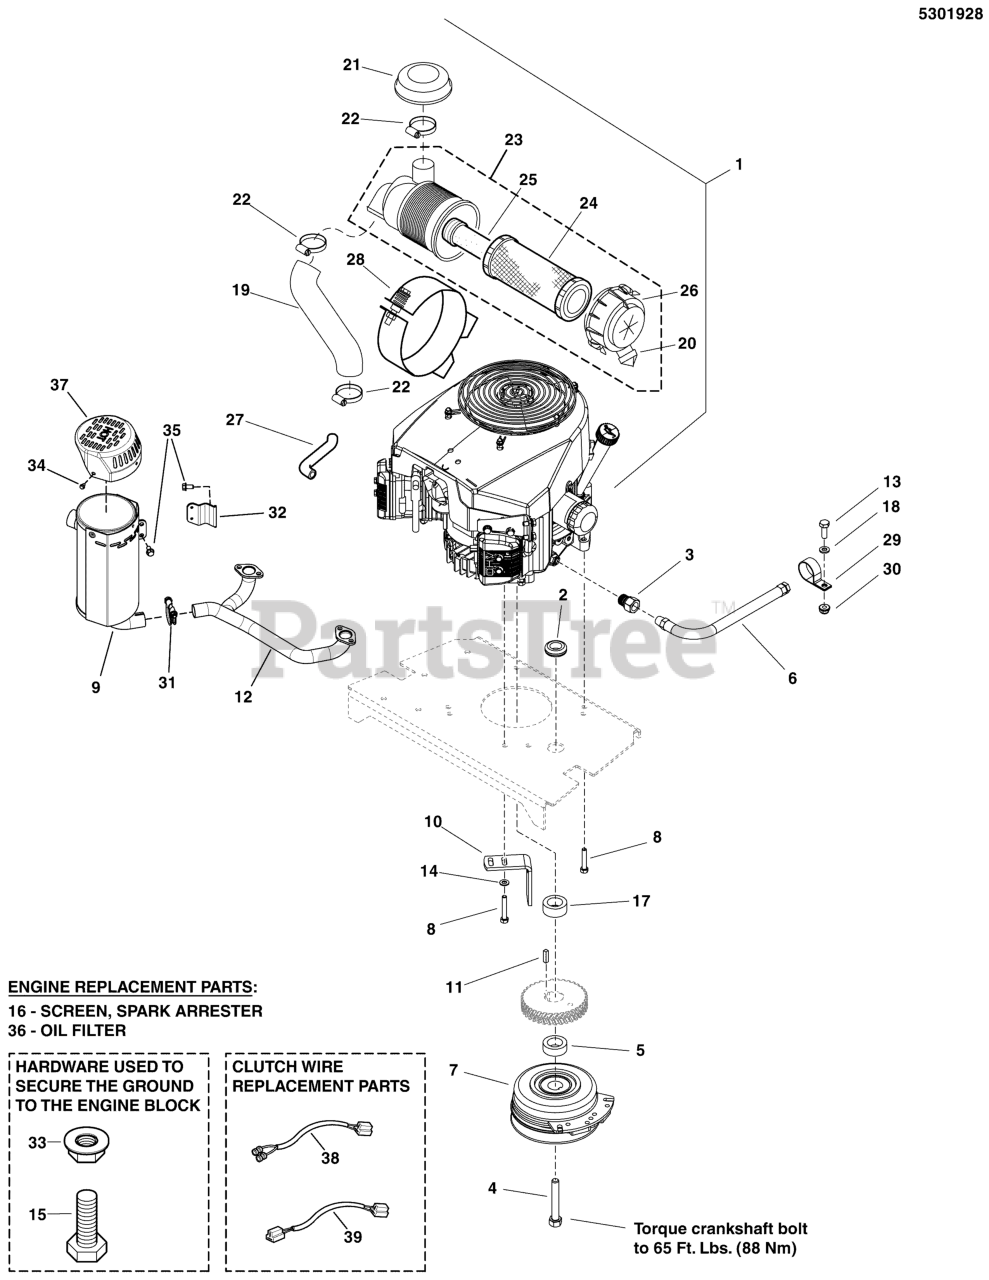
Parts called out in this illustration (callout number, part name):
1	ENGINE, 20HP, KAWASAKI
2	GROMMET, 7/8
3	ADAPTER-OIL DRAIN
4	BOLT, CRANKSHAFT, 7/16 X 2-1/2
5	SPACER, 1.13 X 1.75 X .62
6	HOSE, OIL DRAIN
7	* CLUTCH, 5218-134, WARNER
8	BOLT,HEX FLG, SER GD5 3/8-16X1-1/4,PATCH
9	MUFFLER
10	ANCHOR, CLUTCH - BLK
11	KEY, 1/4 SQ X 1
12	MANIFOLD, EXHAUST
13	BOLT, 1/4-20 X 3/4 GD5 YZ
14	WASHER, 3/8 SAE
15	BOLT, M8-1.25 X 20MM GD8.8
16	SCREEN, SPARK ARRESTER
17	SPACER, 1.13 X 1.75 X .75
18	WASHER, 1/4 SAE
19	AIR INLET TUBE
20	RUBBER DUST CAP
21	RAIN COVER
23	AIR FILTER ASSEMBLY
24	AIR FILTER, ELEMENT, PRIMARY
25	AIR FILTER, ELEMENT, SECONDARY
26	CAP END, FILTER CASE
27	BREATHER TUBE
28	BRACKET, COMPLETE
29	CLAMP, VINYL INSULATED
30	NUT, 1/4-20 HEX NYLOCK FLANGE
31	BAND, CLAMP
32	BRACKET
33	NUT, M8-1.25 SERR. FLANGE, CZ
35	BOLT, FLANGED
36	OIL FILTER
37	COVER-MUFFLER
38	KIT, CLUTCH WIRE REPAIR
39	JUMPER HARNESS, WARNER CLUTCH
